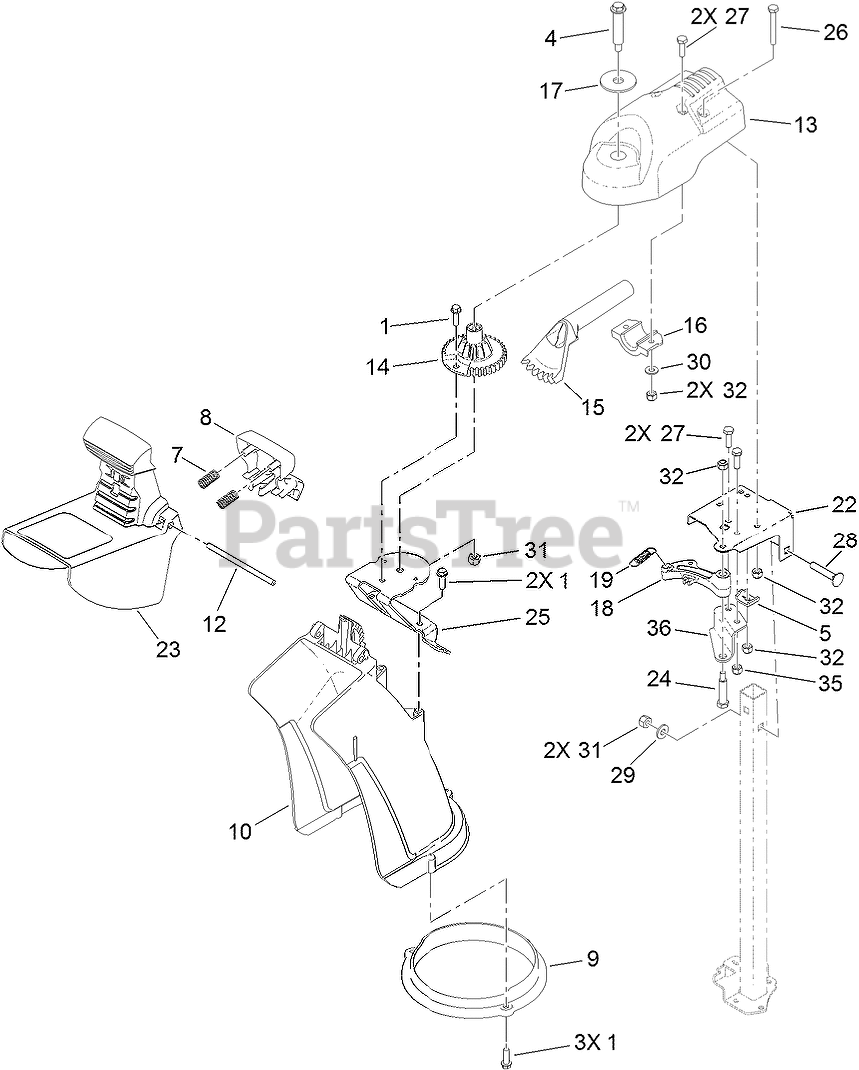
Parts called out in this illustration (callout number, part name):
1	SCREW-HWH
4	BOLT-SHOULDER
5	CLAMP-CABLE
7	SPRING-COMPRESSION
8	TRIGGER-DEFLECTOR
9	RING-CHUTE
10	CHUTE-DISCHARGE
12	ROD-COVER
13	MOUNT-CHUTE, DISCHARGE
14	GEAR-CHUTE
15	GEAR-BEVEL
16	MOUNT-GEAR, BEVEL
17	WASHER-FLAT
18	LATCH-CHUTE
19	SPRING-LATCH, CHUTE
22	BRACKET-SUPPORT, CHUTE
23	DEFLECTOR-CHUTE
24	BOLT-SHOULDER
25	BRACKET-MOUNT, CHUTE
26	SCREW-HH
27	SCREW-HH
28	SCREW-CARR
29	WASHER-FLAT
30	WASHER-FLAT
31	NUT-LOCK, NI
32	NUT-LOCK, NI
35	NUT-LOCK, NI
36	BRACKET-SUPPORT, LATCH
